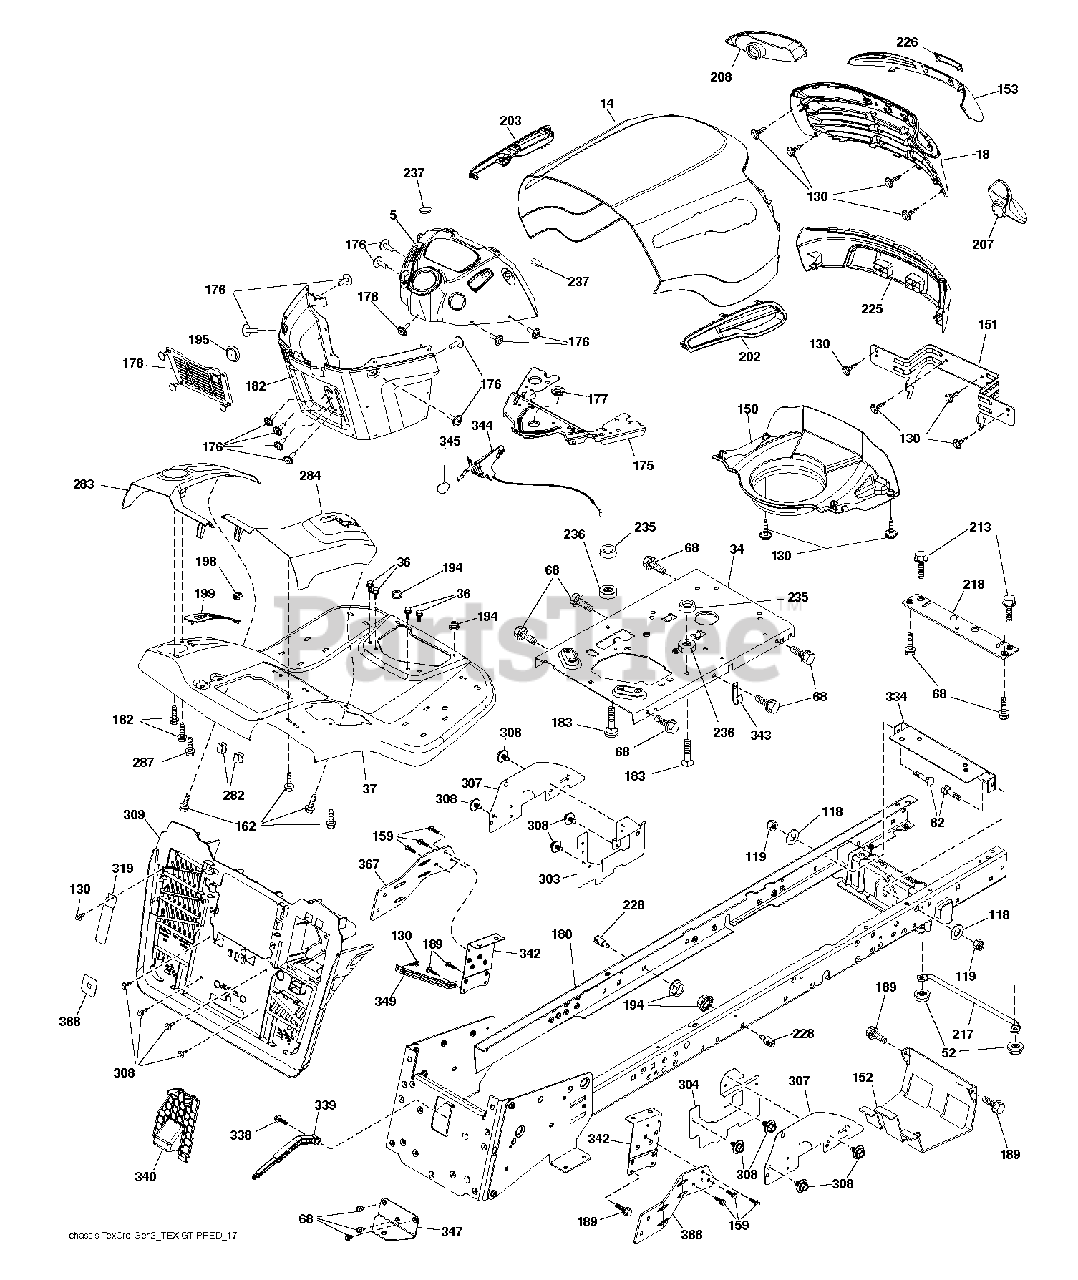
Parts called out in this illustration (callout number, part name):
36	SCREW 5/16"
52	LOCKNUT
119	LOCKNUT
130	SCREW.#10 X 0.750.BOS THREAD
150	PREDATOR.YT.GT.HOOD.A
152	SHIELD BROWNING
159	SCREW, 3/8-16X3/4
162	SCREW.HI-LO.CONSOLE
175	PLATE.CROSSMEMBER.HUSQ
176	SCREW.#10-24X5/8.RN.QU
177	BUSHING,STEERING
178	CARGO.ASM.NET.TXGT.W/C
180	WELDMENT.CHASSIS.TEX.
183	BOLT.5/16-18X1-1/4 FULL THD
189	SCREW
194	NUT LOCK HEX FLANGE 5/16-18
195	PLUG.HOLE.DASH.LOWER.12V.BLK
198	INDICATOR.DECK.LIFT.RED
213	BOLT
217	ROD.PIVOT.HOOD
218	X-PIECE.HOOD.STOP.NON/
228	STUD.FASTNER.W/ANTI-ROTATE
235	SPACER FENDER
236	NUT.CENTERLOCK.5/16-
237	PLUG.MOUNT.CARGO.BLK
282	CLIP.RETAINER.CONSOLE.LT.HUSQ
304	SHIELD.LWR.RH.LT30DECK.PNT.BLK
308	BOLT, 5/16-18 X 1 3/4
309	BACKPLATE.ASM.CRDII.A
